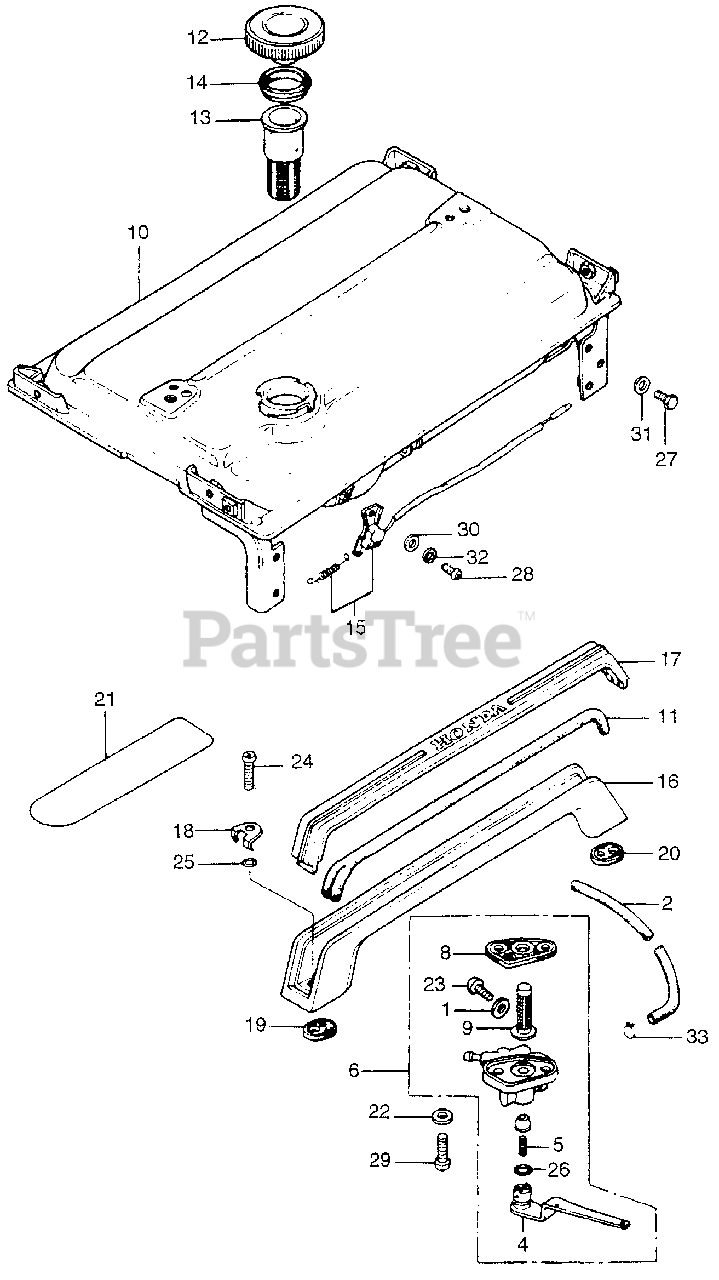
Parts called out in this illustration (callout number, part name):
1	WASHER
2	TUBE, VALVE BREATHER (NOT AVAILABLE)
4	LEVER, VALVE (NA USE ALT:16950-836-703)
4	LEVER, VALVE (NOT AVAILABLE)
5	SPRING, VALVE (NOT AVAILABLE)
6	PETCOCK ASSY. (NOT AVAILABLE)
8	GASKET A, PETCOCK (NOT AVAILABLE)
9	FILTER, CHECK (NOT AVAILABLE)
10	TANK, FUEL *R18* (DAYTONA ORANGE) (NOT AVAILABLE)
11	TUBE, HANDLE BREATHER (NOT AVAILABLE)
12	CAP, TANK (NOT AVAILABLE)
13	FILTER, FUEL
14	RUBBER, FILTER (NOT AVAILABLE)
15	SWITCH ASSY., ENGINE
16	HANDLE, CARRY
17	COVER, HANDLE (NOT AVAILABLE)
18	HOOK, HANDLE COVER
19	GASKET A, HANDLE (NOT AVAILABLE)
20	GASKET B, HANDLE (NOT AVAILABLE)
21	MARK, TREATMENT CAUTION (NOT AVAILABLE)
22	GASKET, FIBER (6MM)
23	SCREW, STOP
24	SCREW, PAN (6X20)
25	O-RING (5X1.5) (NOT AVAILABLE)
26	O-RING (9X1.3) (NOT AVAILABLE)
27	BOLT, HEX. (5X10)
28	SCREW, PAN (3X6)
29	SCREW, PAN (6X16)
30	WASHER, PLAIN (3MM)
31	WASHER, PLAIN (5MM)
32	WASHER, SPRING (3MM)
33	CLIP, TUBE (B6.5)
